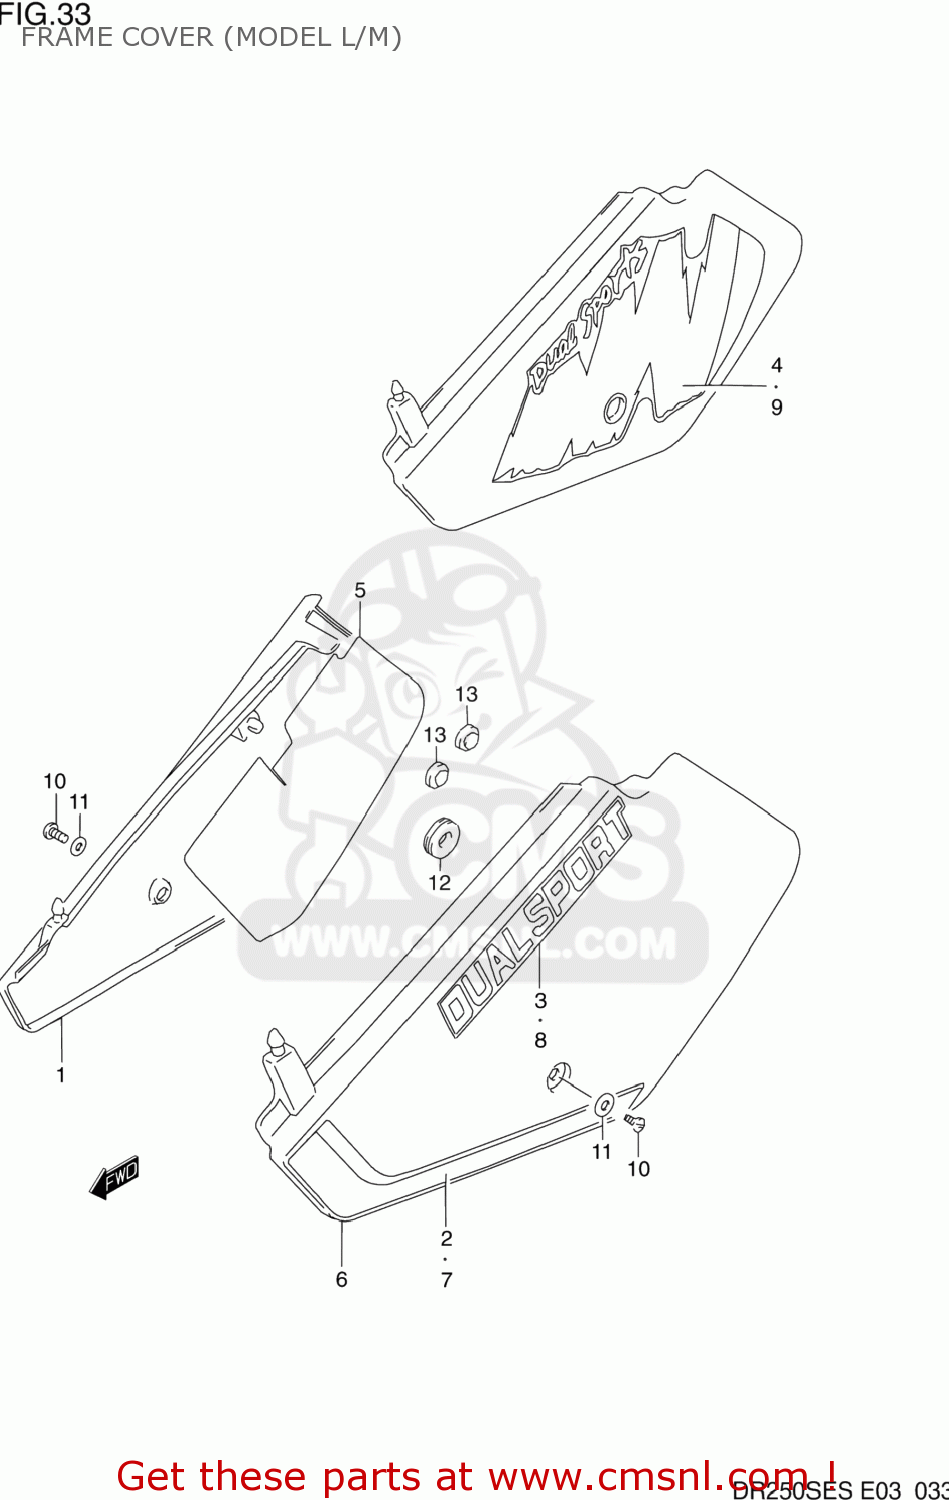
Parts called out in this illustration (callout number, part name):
1	COVER,FRAME,R(WHITE)
2	TAPE,FRAME COVER,RIGHT
3	EMBLEM,FRAME COVER
4	TAPE,FRAME COVER,RIGHT
5	SHIELD,FRAME COVER,R
6	COVER,FRAME,L(WHITE)
7	TAPE,FRAME COVER,LEFT
8	EMBLEM,FRAME COVER
9	TAPE,FRAME COVER
10	SCREW
11	WASHER
12	CUSHION
13	CUSHION
